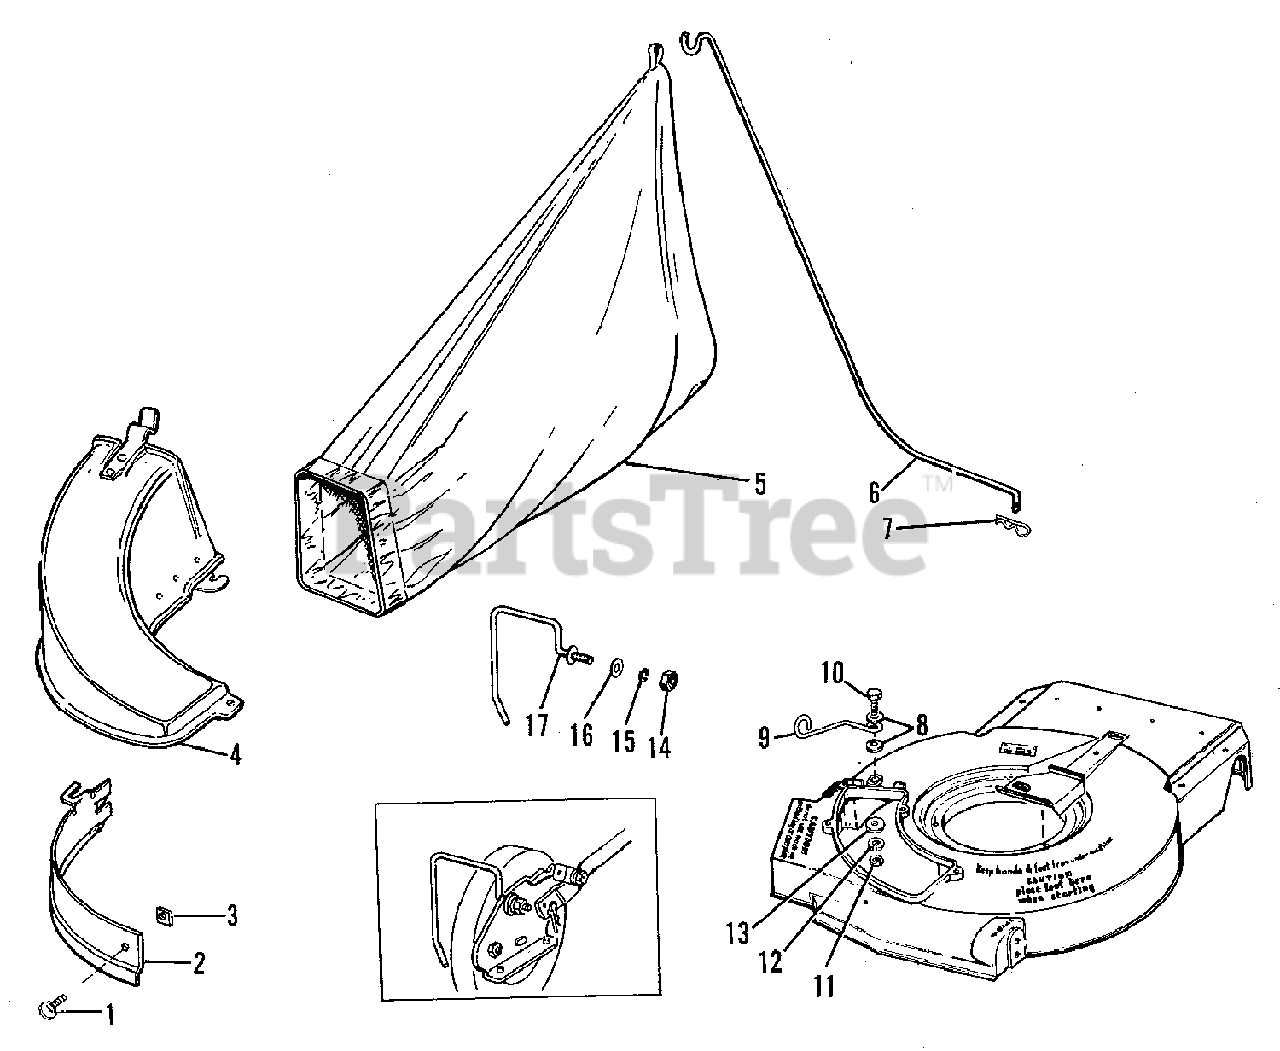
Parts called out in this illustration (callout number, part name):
1	SCREW, Thumb, 1/4-20 x 5/8
6	ROD, Bag Support
7	CLIP, Spring
8	WASHER, Flat, 1/4
10	SCREW, Hex Cap, 1/4-20 x 1
11	NUT, Hex, 1/4-20
12	WASHER, Lock, 1/4
14	NUT, Hex, 5/16-18
15	WASHER, Lock, 5/16"
16	WASHER, Flat, 5/16
